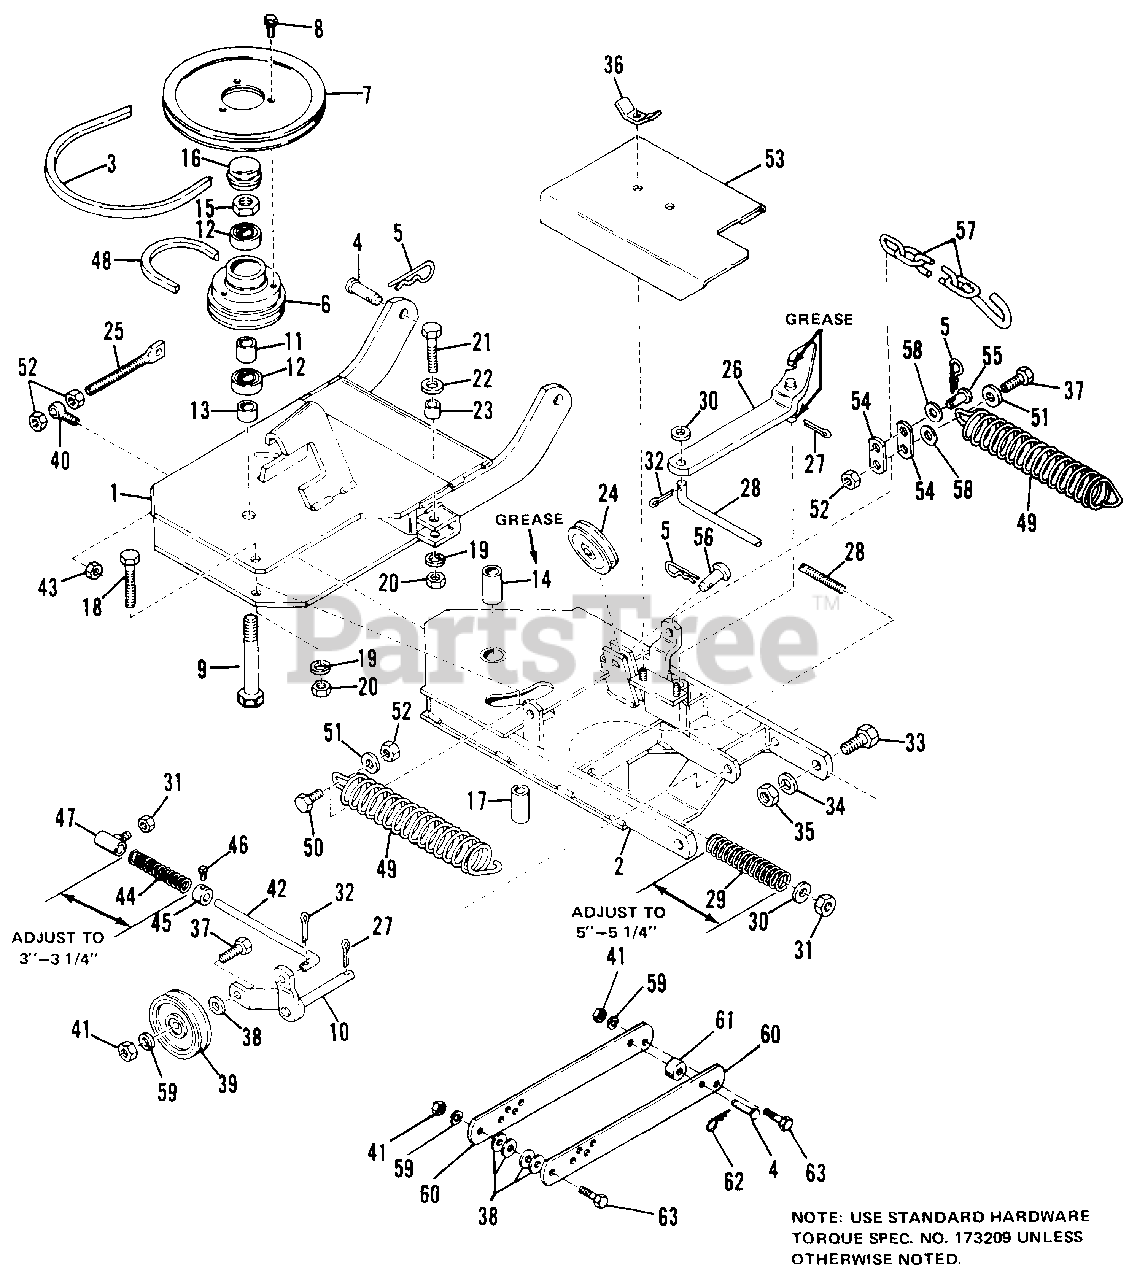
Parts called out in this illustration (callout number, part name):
1	SUPPORT ASSY
2	FRAME ASSY, R.H.
3	BELT, "V"
5	CLIP, Spring
8	SCREW, Hex, Wshr Hd., Taptite, 5/16-18 x 5/8
9	BOLT ASSY
10	LEVER ASSY
12	BEARING, Ball
15	NUT, Hex, Full Lock, 3/4-10
16	CAP, Hub
18	CAPSCREW, Hex Hd., 1/2-13 x 3
19	LOCKWASHER, Spring, 1/2
20	NUT, Hex, 1/2-13
21	CAPSCREW, Hex Hd., 1/2-13 x 2-1/4
22	WASHER, Plain, 7/16
25	BOLT ASSY
26	LATCH ASSY
27	PIN, Cotter
30	WASHER, Plain, 1/4
31	NUT, Hex, Lock, 5/16-18
32	PIN, Cotter, 3/32 x 5/8
33	CAPSCREW, Hex Hd., 5/8-11 x 1-1/2
35	NUT, Hex, Full Lock, Jam
36	NUT, Wing, 5/16-18
37	CAPSCREW, Hex Hd., 3/8-16 x 1-1/4
38	WASHER, Plain, 3/8
39	PULLEY, Idler
40	BOLT, Eye
41	NUT, Hex, 3/16-18
43	NUT, Hex, Lock, 3/8-24
45	COLLAR, Set
46	SCREW, Set, Sq. Hd., Cup Pt., 1/4-20 x 3/8, Gr. 8
47	GUIDE ASSY, Rod
48	BELT, "V"
49	SPRING, Tension
50	CAPSCREW, Hex Hd., 3/8-16 x 1
51	WASHER, Plain, 5/16
52	NUT, Hex, Full Lock, 3/8-16
54	LINK, Mower Lift
57	CHAIN ASSY
59	LOCKWASHER, 3/8
60	BAR, Lift
62	PIN, Quick, 1-7/8
63	CAPSCREW, Hex Hd., 3/8-16 x 1-1/2
